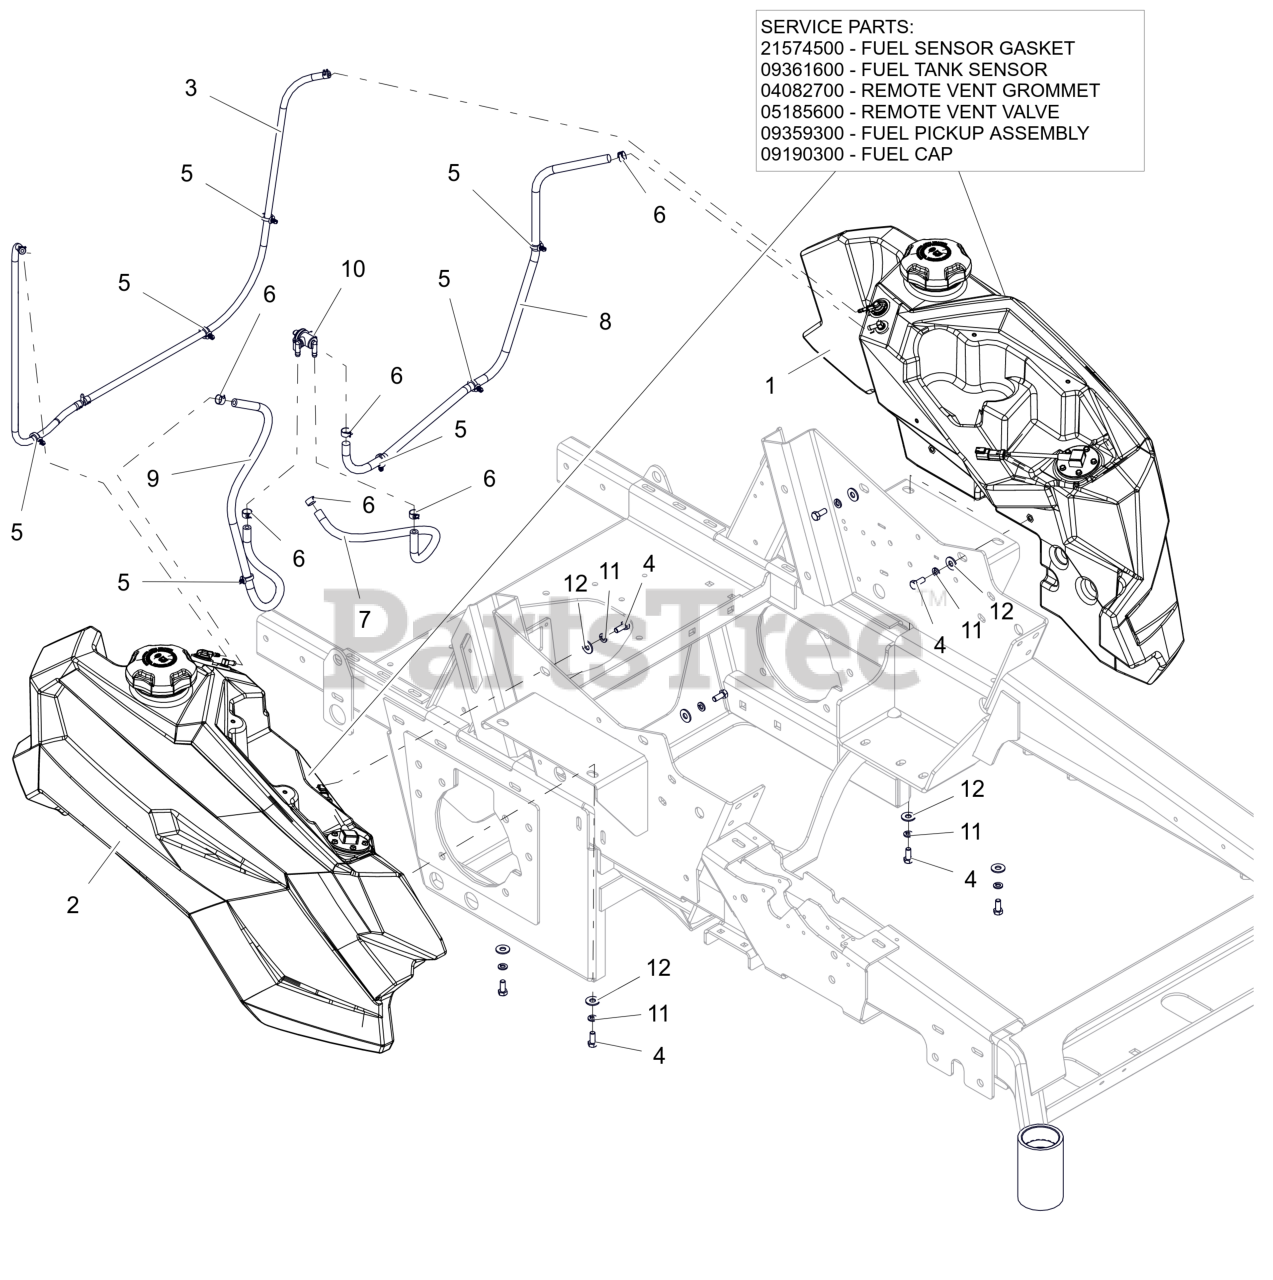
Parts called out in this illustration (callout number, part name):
1	ASM, LH FUEL TANK
1	FUEL TANK SENSOR GASKET
1	FUEL TANK SENSOR
1	GROMMET, REMOTE VENT NITRILE
1	VALVE, COMBINATION VENT 3/16
1	FUEL PICKUP ASSEMBLY
1	CAP, FUEL - 3.50 RATCHET INLET VENT
2	ASM, RH 421 FUEL TANK
3	ASM- PT300/500/600 VENT LINE
4	BLT,HEX .31-18X.75 G5 ZCC
5	CLIP- PUSH-IN X-MAS TREE CABLE
6	CLAMP, FUEL LINE
7	1 INCH OF HOSE, .25 LOW-PERM BULK GAS
8	1 INCH OF HOSE, .25 LOW-PERM BULK GAS
9	1 INCH OF HOSE, .25 LOW-PERM BULK GAS
10	VALVE, FUEL - WITH MAGNET
11	WSHR,LK-REG .312X.078 ZCC
12	WSHR,FLT .375X.875X.083 ZCC
